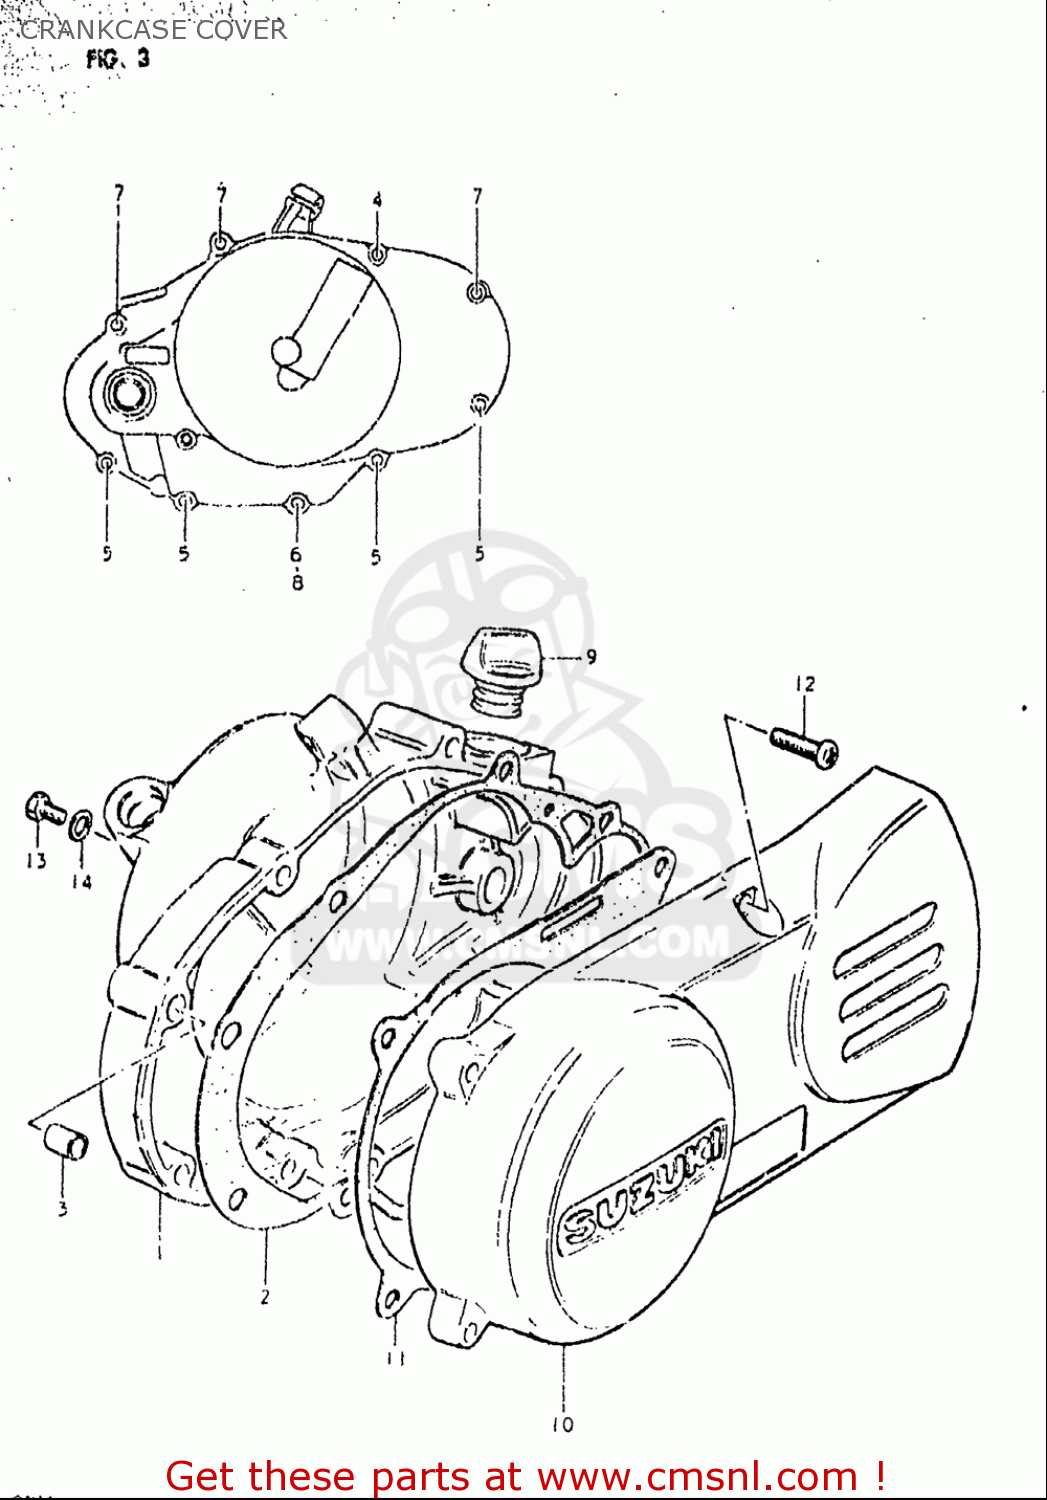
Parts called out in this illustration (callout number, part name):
2	GASKET,CLUTCH COVER (NAS)
3	PIN
4	SCREW
5	SCREW
6	SCREW
7	SCREW
8	GASKET(6.2X11X1).2 (NAS)
9	PLUG
10	COVER,MAGNETO
11	GASKET,MAGNETO COVER (NAS)
12	SCREW
13	SCREW(6X10)
14	GASKET(6.2X11X1) (NAS)
